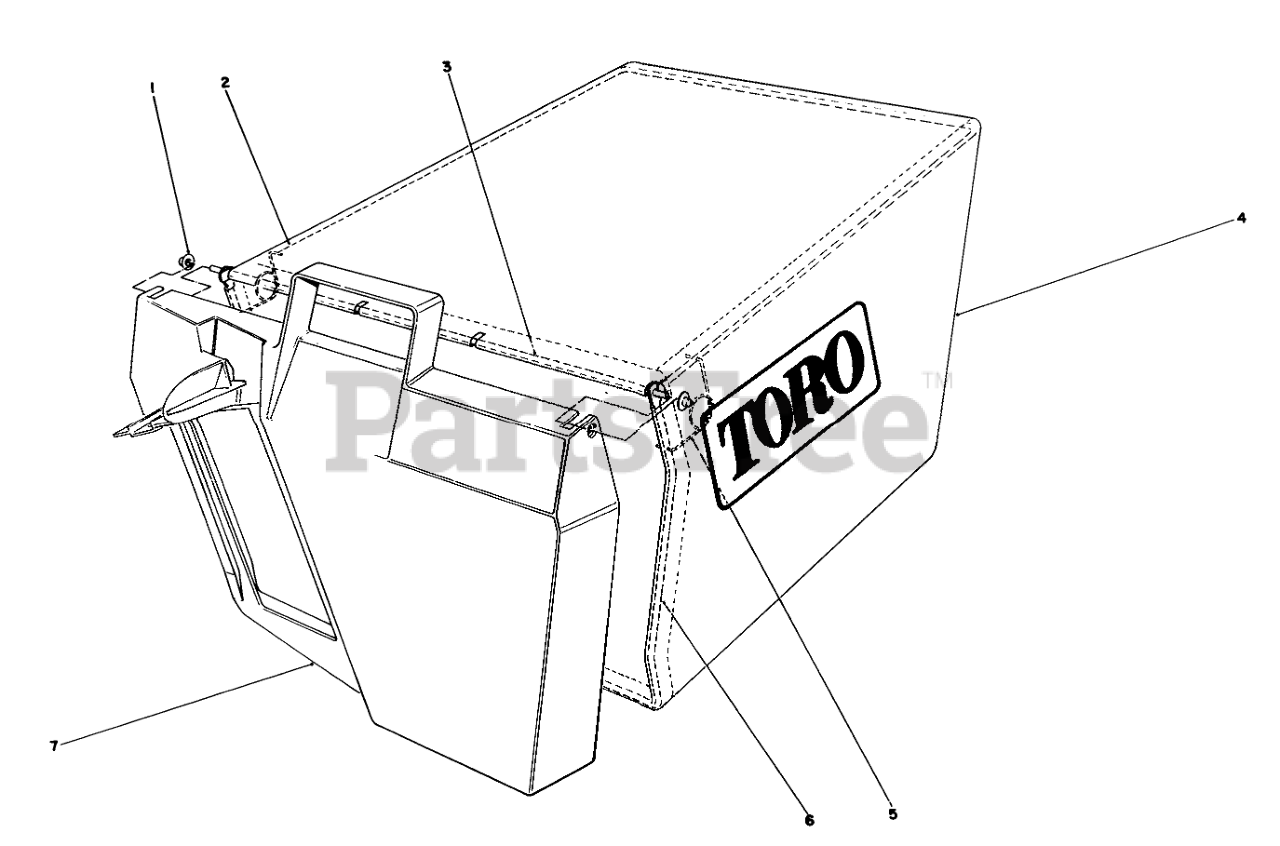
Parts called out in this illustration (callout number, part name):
1	NUT-PUSH
2	FRAME-BAG, UPPER
3	HINGE-DOOR, BAG
4	BAG-GRASS
5	SPRING
6	BAG FRAME
7	BAG DOOR
